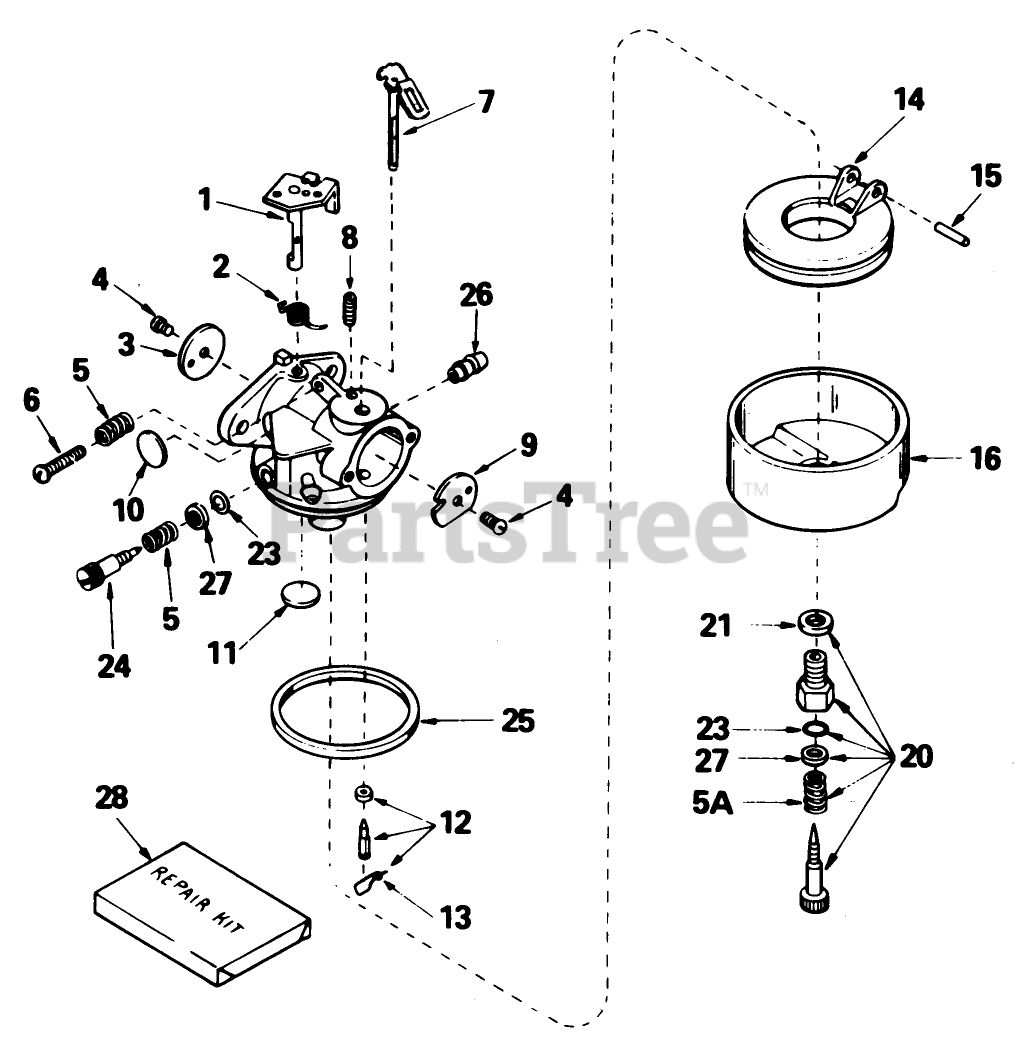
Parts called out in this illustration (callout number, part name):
1	Shaft/Lever-Throttle
2	Spring-Return, Throttle
3	Shutter-Throttle
4	Screw-Shutter
5	Spring-Tension
5A	Spring
6	Screw-Throttle Crack Screw / Idle Speed
7	Choke Shaft and Lever ASM
8	Spring-Positioning, Choke
9	Shutter-Choke
10	Plug-Welch, Idle Mixture Well
11	Plug-Welch, Atmospheric Vent
12	Inlet Needle, Seat Clip Assy. (Incl. No. 13)
13	Clip-Spring
14	Float
15	Shaft-Float
16	Bowl-Float (no drain)
20	Adjustment Screw Assy.,Main (Incl. Ref. #5A,21,23 30)
21	Washer-Bowl Nut
23	ORing
24	Screw-Idle Mix
25	O Ring-Bowl, Float
26	Fitting-Fuel
27	Washer
28	Kit-Repair
